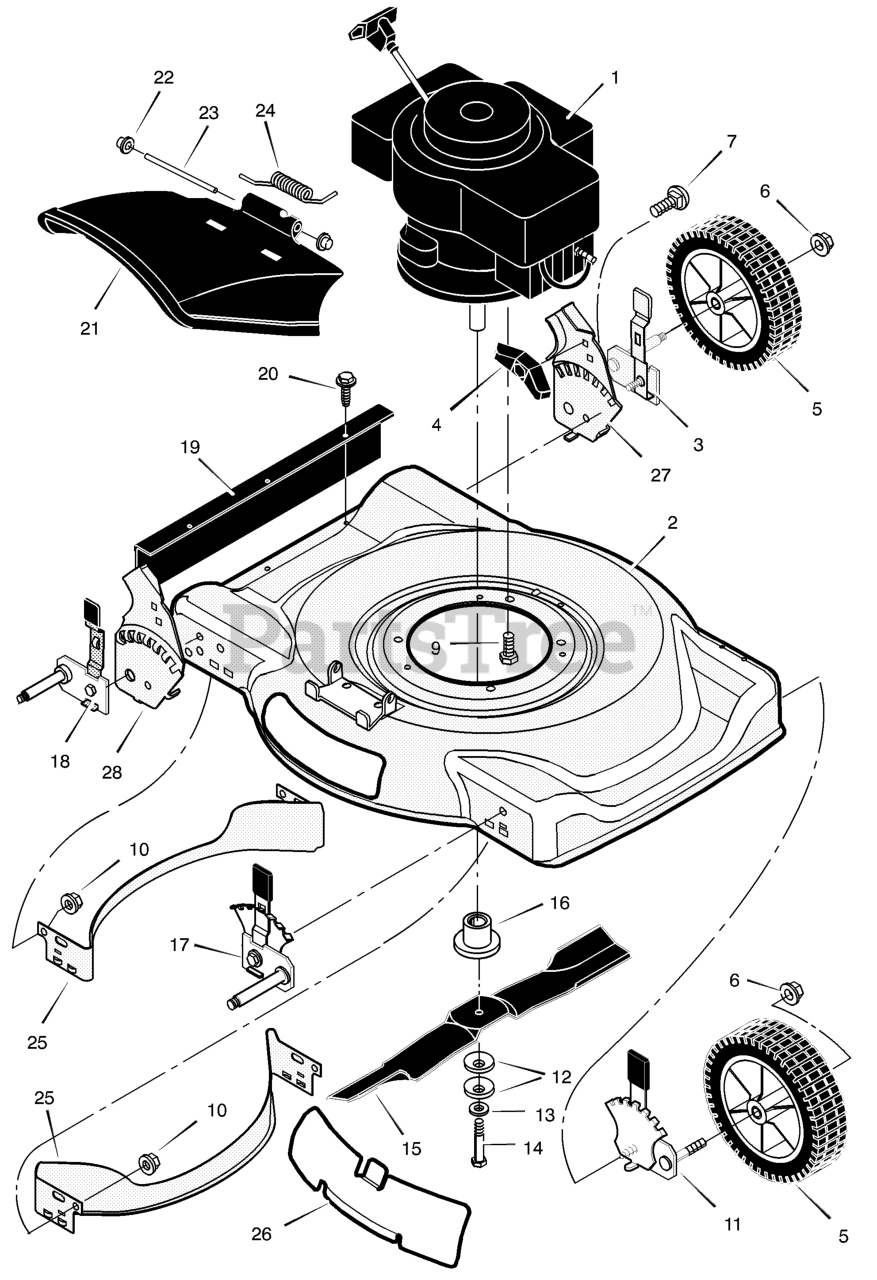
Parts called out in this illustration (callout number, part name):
1	Engine
2	Housing
3	Height Adjuster, Left Rear
5	Wheel and Tire
6	Locknut, Flange
7	Bolt, Carriage
9	Bolt, Engine
10	Nut
11	Height Adjuster, Left Front
12	Washer, Belleville
14	Bolt, Hex
15	Blade (3-N-1)
16	Adapter, Blade
17	Height Adjuster, Right Front
18	Height Adjuster, Right Rear
19	Guard, Rear
21	Deflector, Chute
22	Push-On Cap
23	Pin, Pivot
25	Baffle
26	Plate, Mulcher
27	Bracket, Left Handle
28	Bracket, Right Handle
